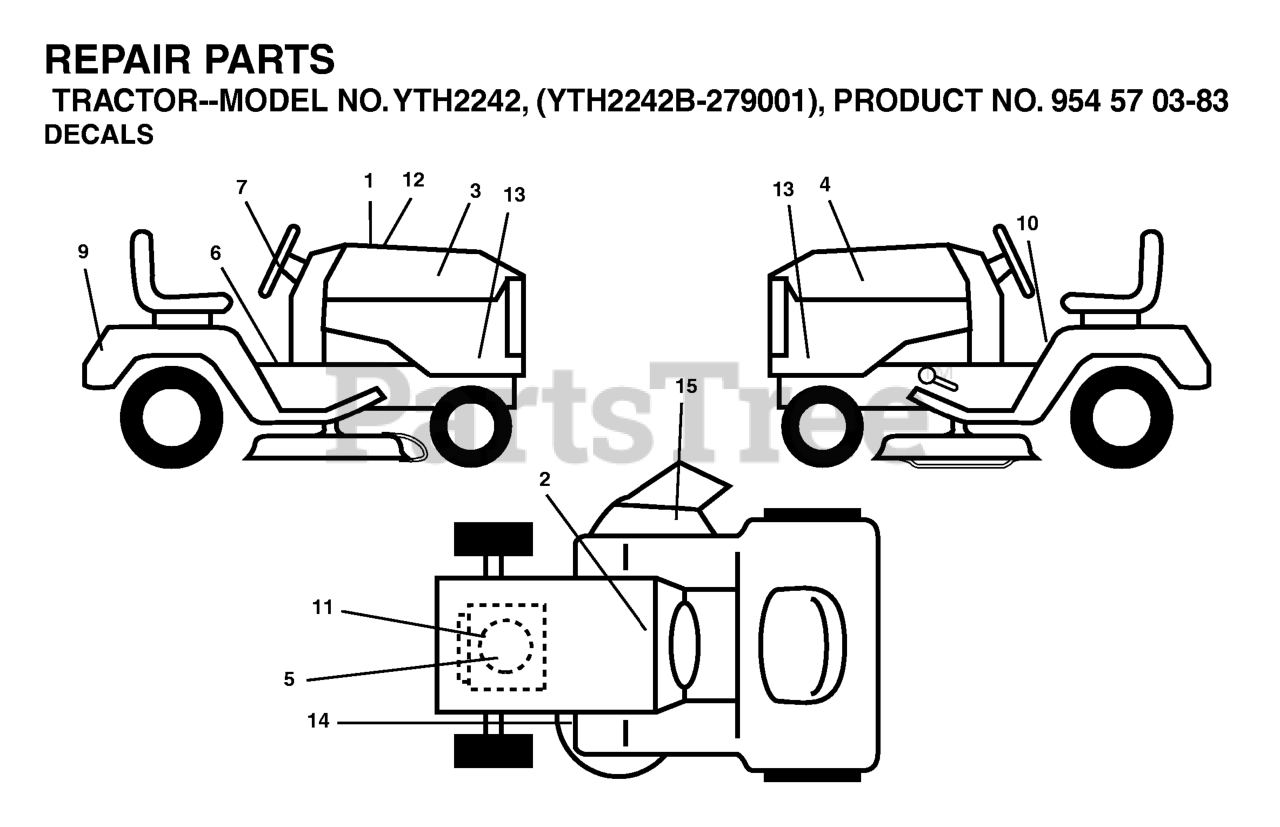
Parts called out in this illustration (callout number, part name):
1	DECAL HOOD CUST. RESP.
2	DECAL BTRY SYMBOLS
3	DECAL.HOOD.RH
4	DECAL.HOOD.LH
5	DECAL, ENGINE
7	DECAL.WHEEL.STEERING.HUSQ.PERM
9	DECAL, FENDER
13	SIDE PANEL DECAL
14	DECAL V BELT SCHEMATIC
15	DECAL DECK "B" 42"
